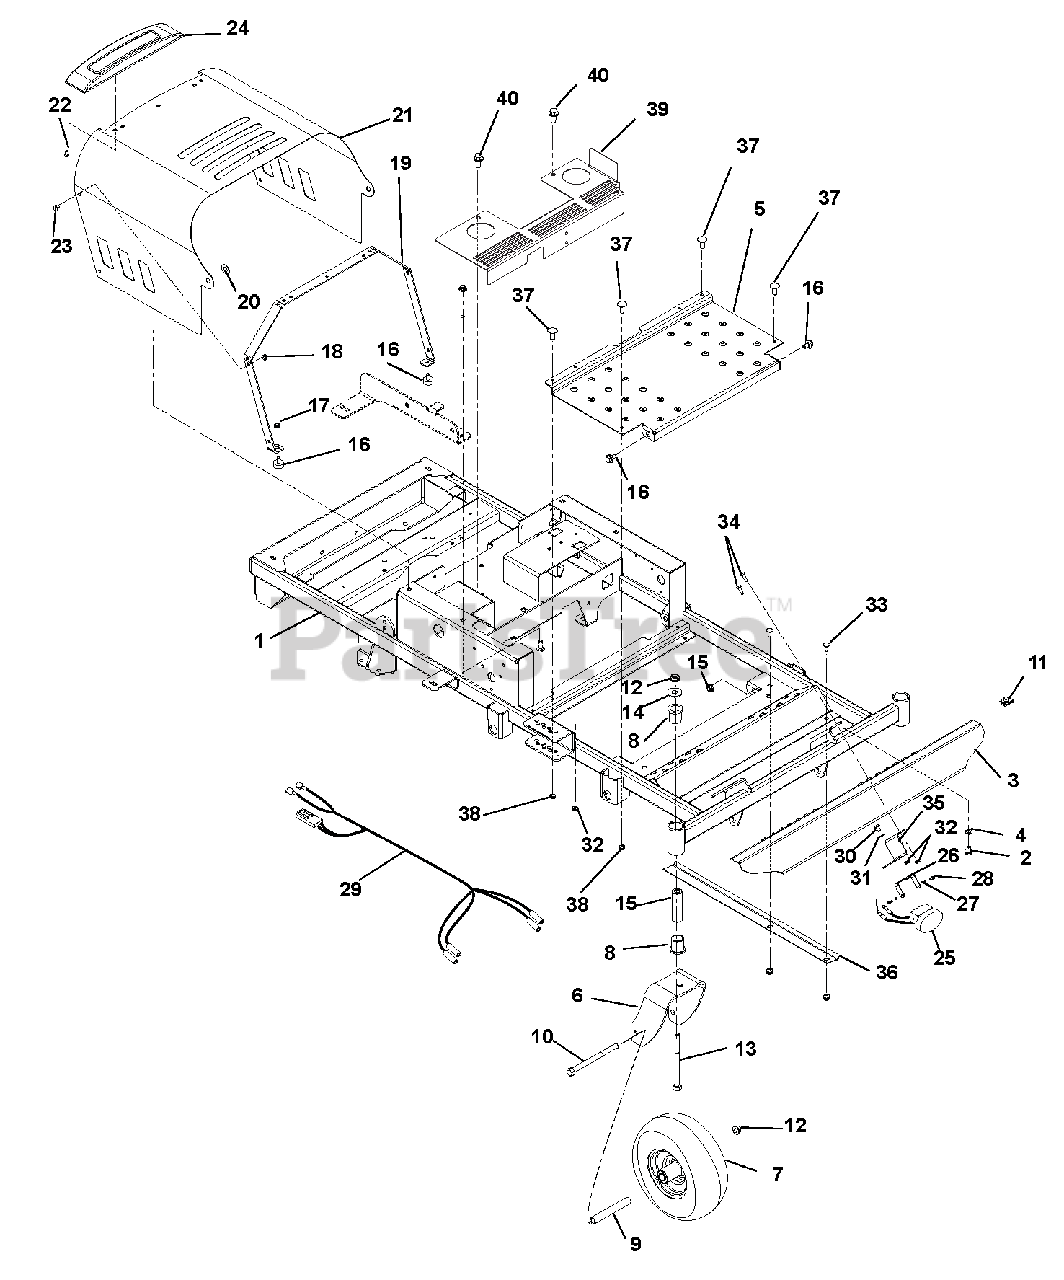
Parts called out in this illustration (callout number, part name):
1	WMT, ZTXL FRAME
2	@BLT-HEX .38-16X1.00 GR5 YWZC
3	WMT, FOOTREST
4	@WSHR-LK .38X.094 REG YWZC
5	PANEL WLDMT, FOOT PLATE
6	WMT, CASTER FORK
7	TIRE/WHEEL ASSY, 11X4-5
8	BSHG-FLG 1.00X1.25X1.50X1.50EP
9	SPACER, ROLLED WHEEL
10	@BLT-HEX .50-13X6.50 GR5 YWZC
11	NUT-RTNR .375-16X.37
12	@NUT-LK-TOP-FLG .50-13 YWZC
13	@BLT-HEX .50-13X5.00 GR5 YWZC
14	WSHR-FL-STL.511X1.441X.125 YWZ
15	SPACER, CASTER .50X1.00X1.84
16	BUMPER, RUBBER
17	@NUT-LK-TOP-FLG .31-18 YWZC
18	@NUT-LK-TOP-FLG .25-20 YWZC
19	HOOD STRAP
20	WSHR-FL-NYL .518X1.000X.080
21	HOOD-ZTXL
22	SCR-.25X.62 PN HD BOSSSCREW YZ
23	@BLT-RDHDSQNK .25-20X.50 G5YZ
24	TRIM-ZOOM XL HOOD ARIENS
25	KIT, ZOOM/ZT XL LIGHT
26	WMT, LIGHT BRACKET
27	WSHR-LK 4MMX1MM REG CL ZINC
28	SCREW-M4X.07X8 SHCS CLZNC
29	HARNESS,MINI-Z HEADLIGHT
30	SCR-CAP BTHD.31-18X.50 GR5 YZ
31	@WSHR-LK .31X.078 REG YWZC
32	@NUT-LK-NYL-FLG .25-20 YWZC
33	@BLT-RDHDSQNK .31-18X.75 G5YZ
34	@BLT-HEX .25-20X.75 GR5 YWZC
35	BRACKET, LIGHT MOUNT
36	BRACKET, LIGHT HARNESS
37	@BLT-HEX .31-18X1.00 GR5 YWZC
38	@NUT-LK-NYL-FLG .31-18 YWZC
39	BRACKET, XL CE FAN GUARD
40	@SCR-TAP .38-16X.50 HWH TR YWZ
